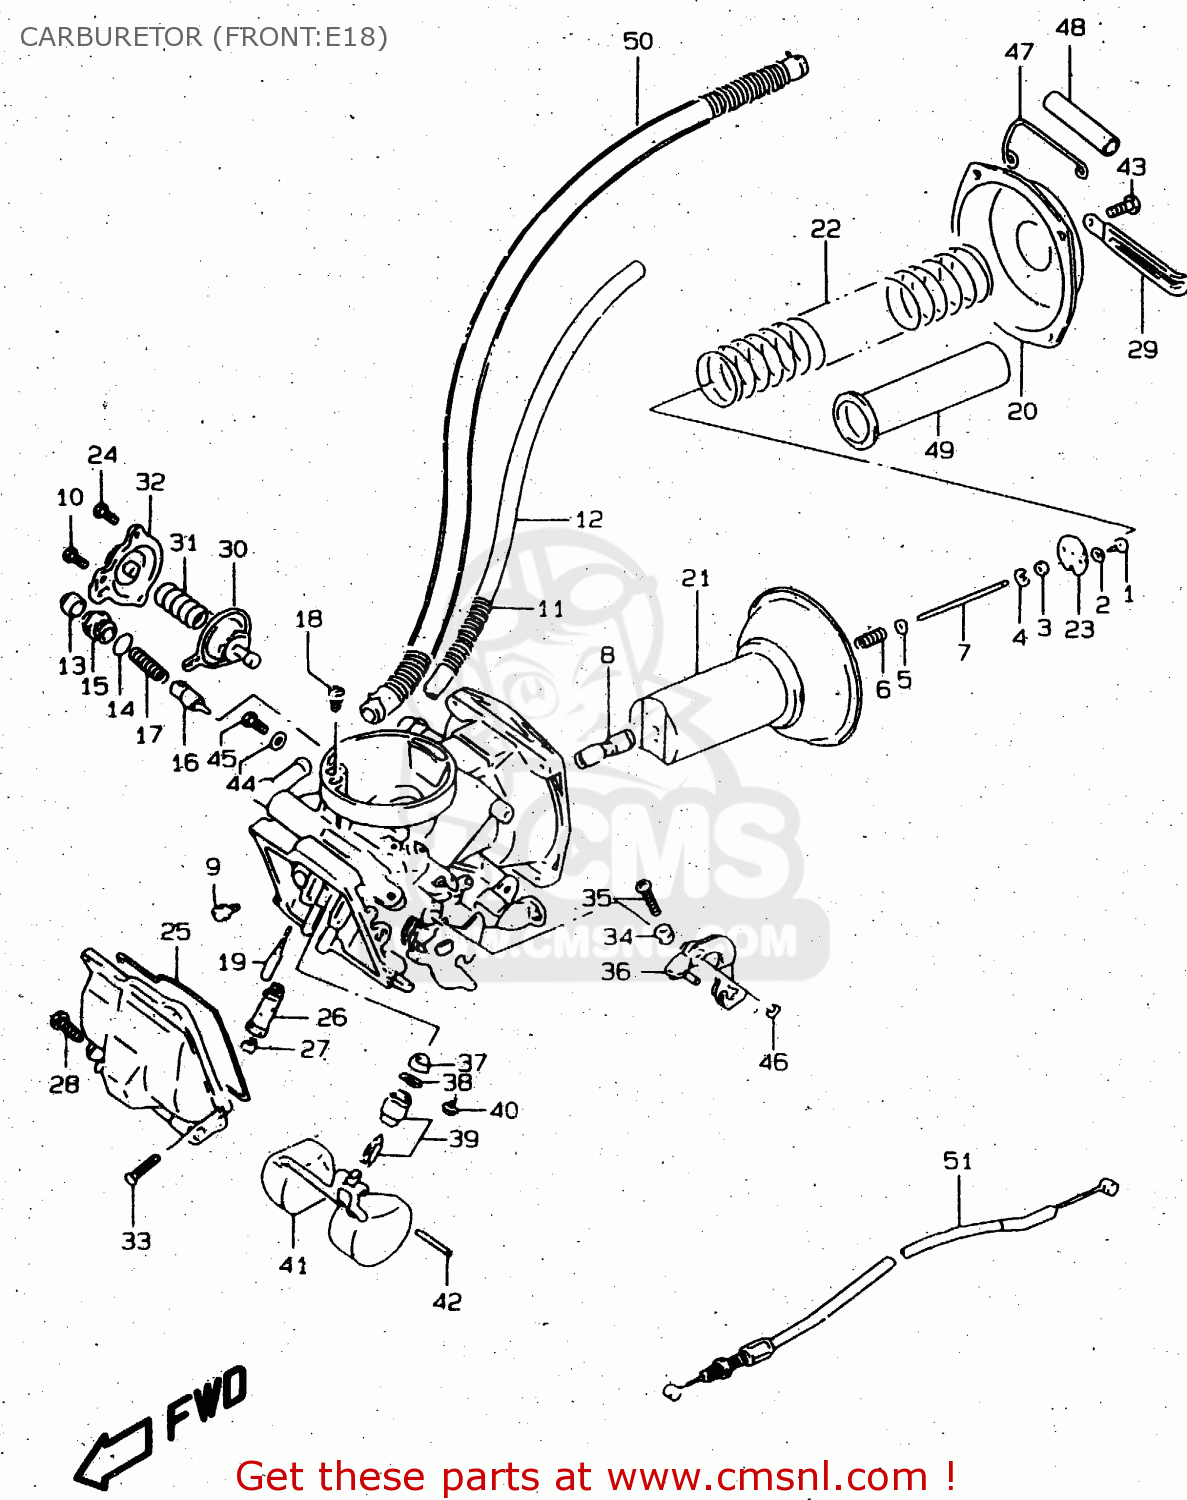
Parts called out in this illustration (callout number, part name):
1	SCREW
2	WASHER,LOCK
3	RING
4	CLIP
5	WASHER
6	SPRING
7	NEEDLE, JET (5D48-3)
8	JET,NEEDLE(P-1)
9	SCREW
10	SCREW
11	SPRING
12	HOSE(5X8.2X600)
13	CAP
14	O RING
15	HOLDER,GUIDE
16	PLUNGER,STARTER
17	SPRING
18	JET,AIR(65)
19	JET,PILOT(40)
20	COVER
21	DIAPHRAGM ASSY
22	SPRING,DIAPHRAGM
23	PLATE
24	SCREW,UPPER
25	O RING,FLOAT CHAMBER
26	HOLDER,MAIN JET
27	JET,MAIN(97.5)
28	SCREW,DRAIN
29	CLAMP(L:65)
30	DIAPHRAGM ASSY
31	SPRING
32	COVER
33	SCREW
34	NUT
35	SCREW
36	LEVER,ASSY
37	FILTER
38	O-RING,NEEDLE VALVE
39	VALVE ASSY,NEEDLE
40	SCREW
41	FLOAT
42	PIN,FLOAT
43	SCREW
44	GASKET,DRAIN PLUG (NAS)
45	SCREW
46	E RING
47	CLIP
48	HOSE(6X10X600)
49	RING
50	HOSE ASSEMBLY
51	CABLE,IDLE SYNCRO
